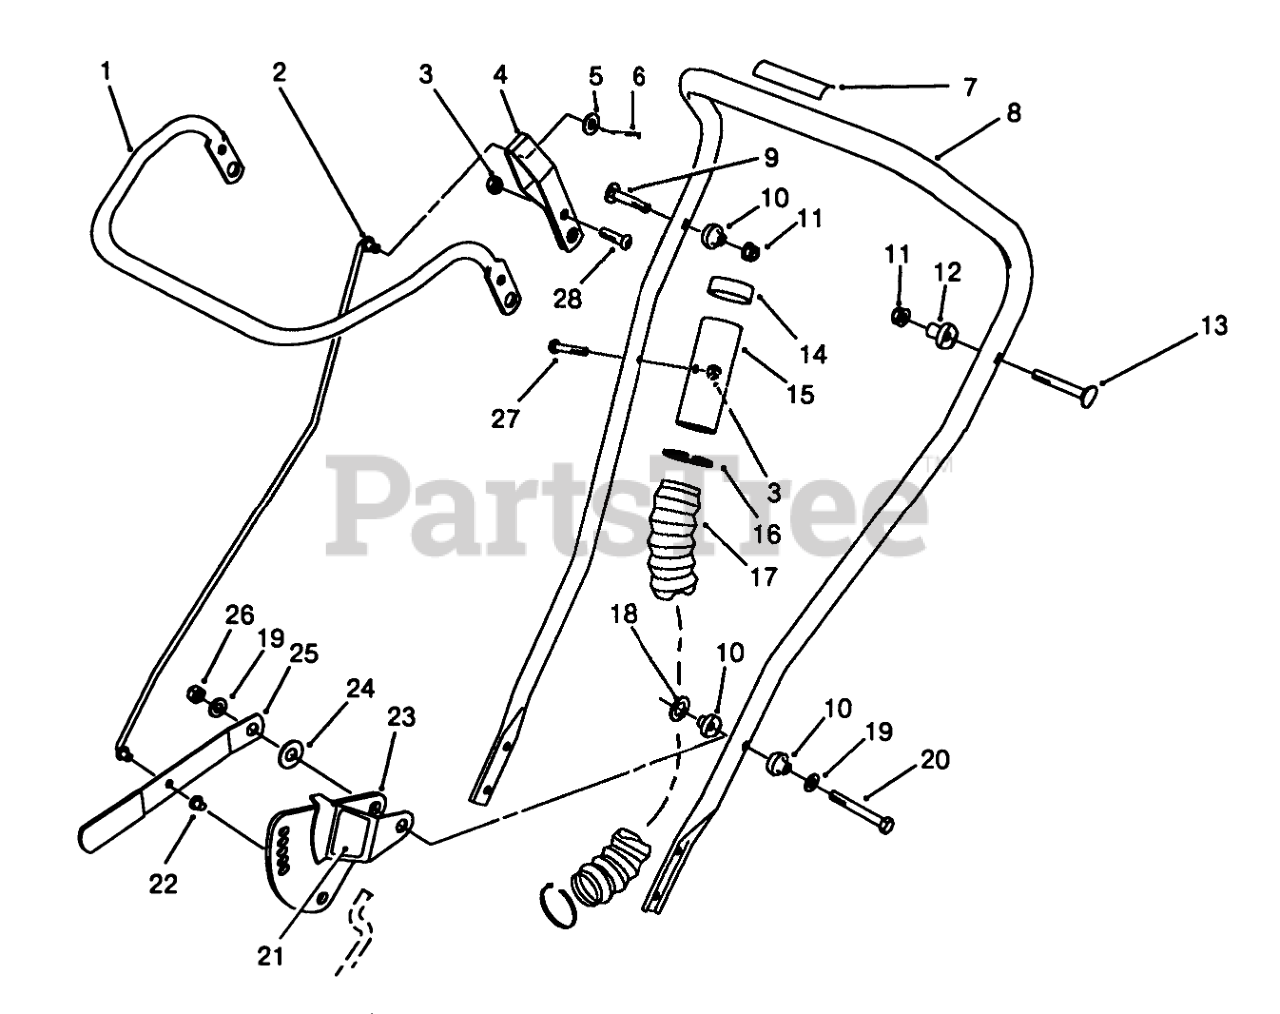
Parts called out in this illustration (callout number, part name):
1	Bar-Control
2	UPPER CONTROL ROD
3	NUT-LOCK, NI
4	CONTROL BAR BRKT.
5	WASHER-FLAT
6	PIN-COTTER
7	DECAL
8	UPPER HANDLE
9	SCREW-HANDLE
10	PIVOT SPACER
11	NUT-LOCK, NI
12	SPACER-SUPPORT
13	5/16-18 X 2 HNDLE SCREW
14	BLACK CAPLUG
15	AIR CLNR HOSE TIP
16	TIE-CABLE
17	AIR CLEANER HOSE
18	WASHER
19	WASHER-PLAIN
20	SCREW-HH
21	DECAL
22	PUSHNUT
23	ADJ.PLATE WA
24	WASHER
25	ADJ.HANDLE
26	NUT-LOCK, NI
27	SCREW-HH
28	SCREW-HSBH
